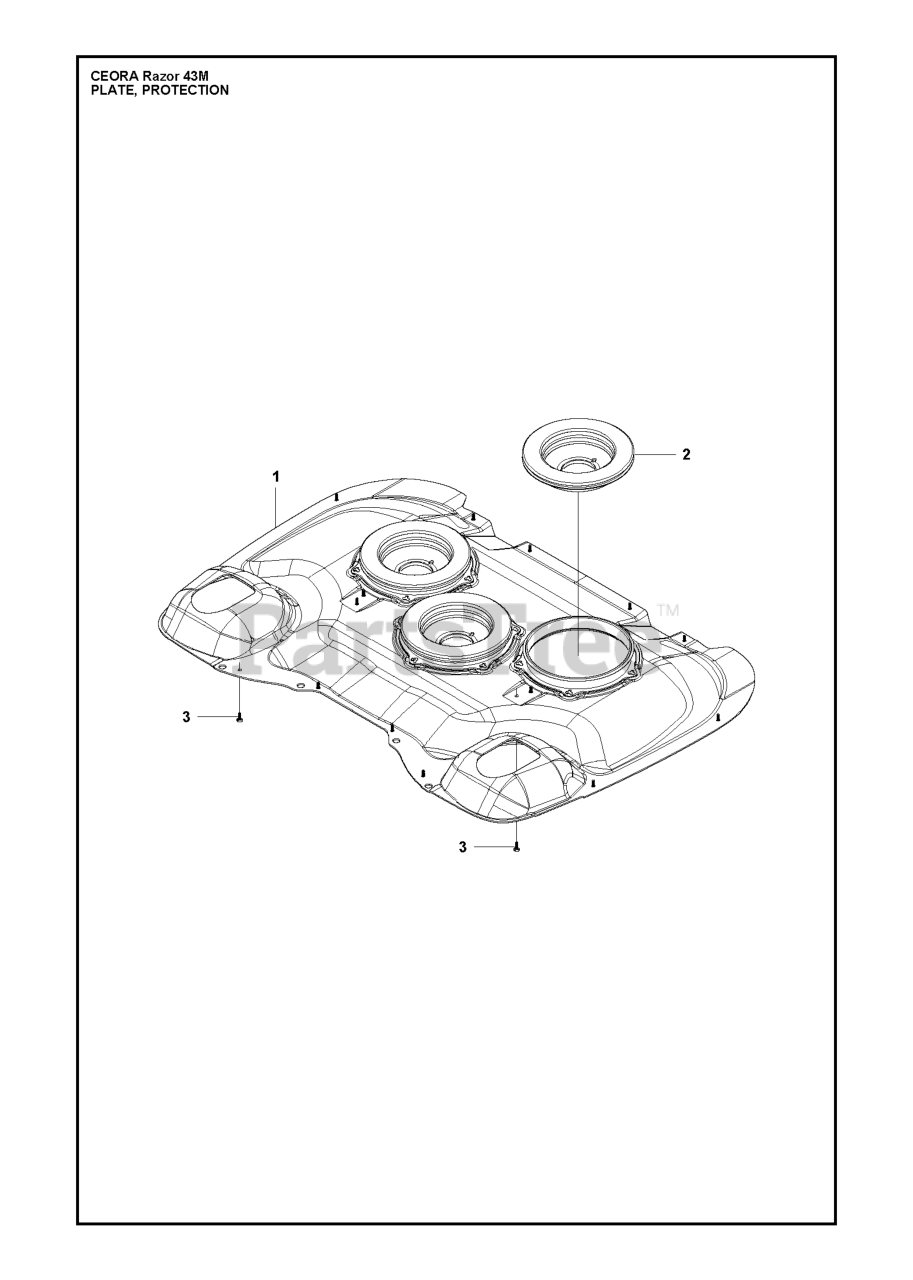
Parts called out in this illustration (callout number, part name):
1	PLATE ASSY PROTECTION - CUTTIN
2	BELLOWS CUTTING MOTOR
3	SCREW ITXPANT
